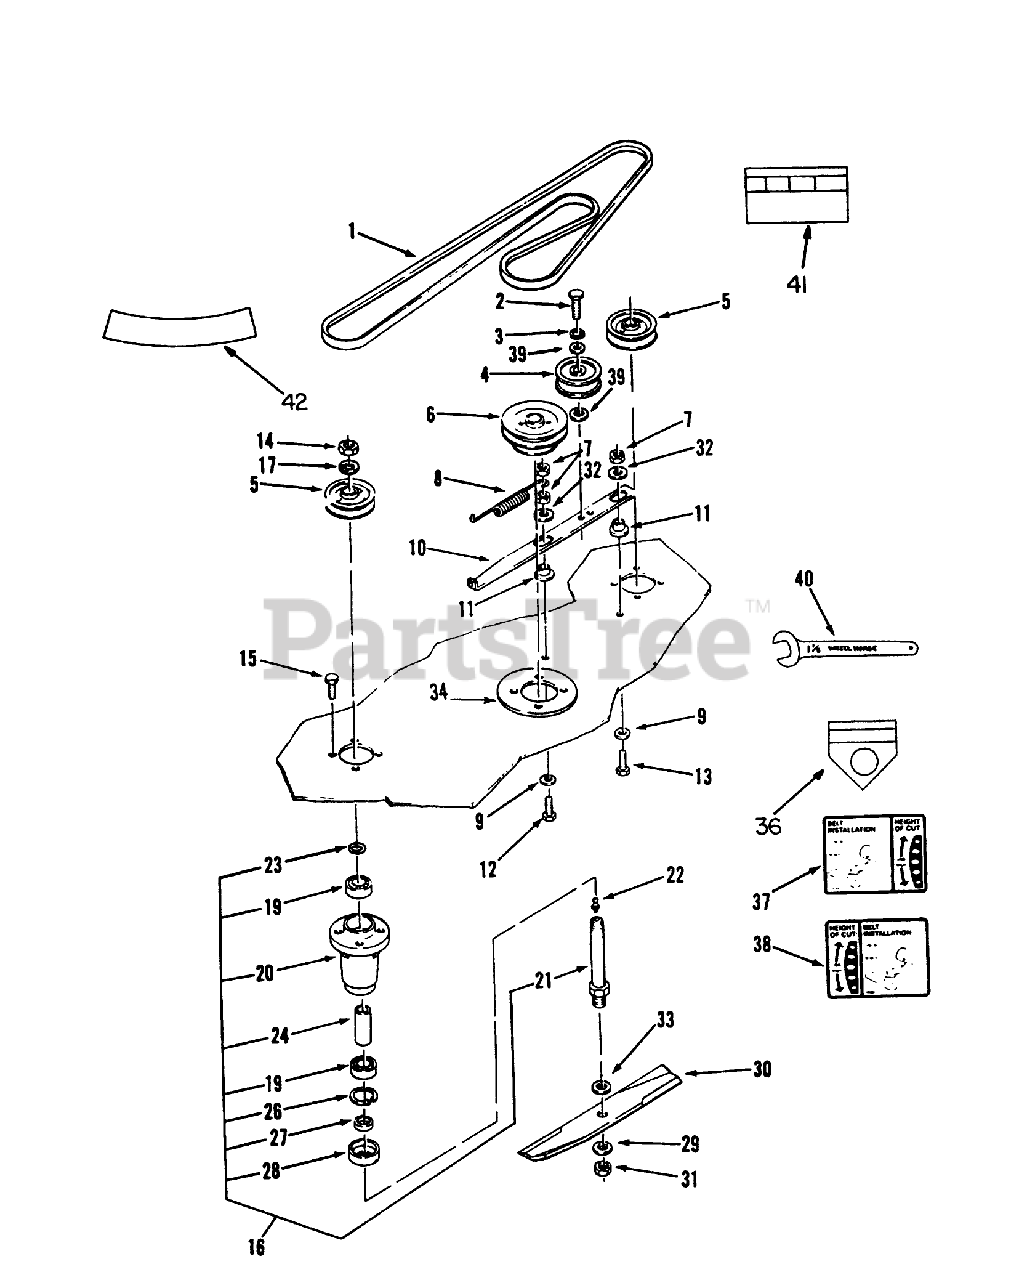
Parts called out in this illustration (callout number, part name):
1	V-BELT
2	SCREW-HH
3	WASHER-LOCK
4	Pulley
5	PULLEY-BLADE, DRIVE
6	PULLEY-MOWER, 48IN
7	NUT-LOCK, NI
8	SPRING-EXTENSION
9	WASHER
10	BAR-IDLER SUPPORT
11	SPACER-BUSHING
12	SCREW-HH
13	SCREW-HH
14	NUT-JAM
15	Bolt
16	Spindle Assembly (Inc. Ref. #19-28)
17	WASHER-LOCK
19	BEARING-BALL
20	HOUSING-SPINDLE
21	SHAFT-SPINDLE
22	FITTING-GREASE
23	O RING
26	RING-RETAINING
27	SPACER-BLADE
28	CUP-SPINDLE
29	WASHER-FLAT
30	Blade
31	NUT-JAM
32	WASHER
33	Washer
34	PLATE-SPINDLE
36	DECAL-DANGER
37	DECAL-HEIGHT & BELT
38	DECAL-HEIGHT & BELT
39	WASHER-FLAT
40	Spindle Wrench
41	DECAL-DANGER, THROWN OBJECT
42	DECAL - DANGER
